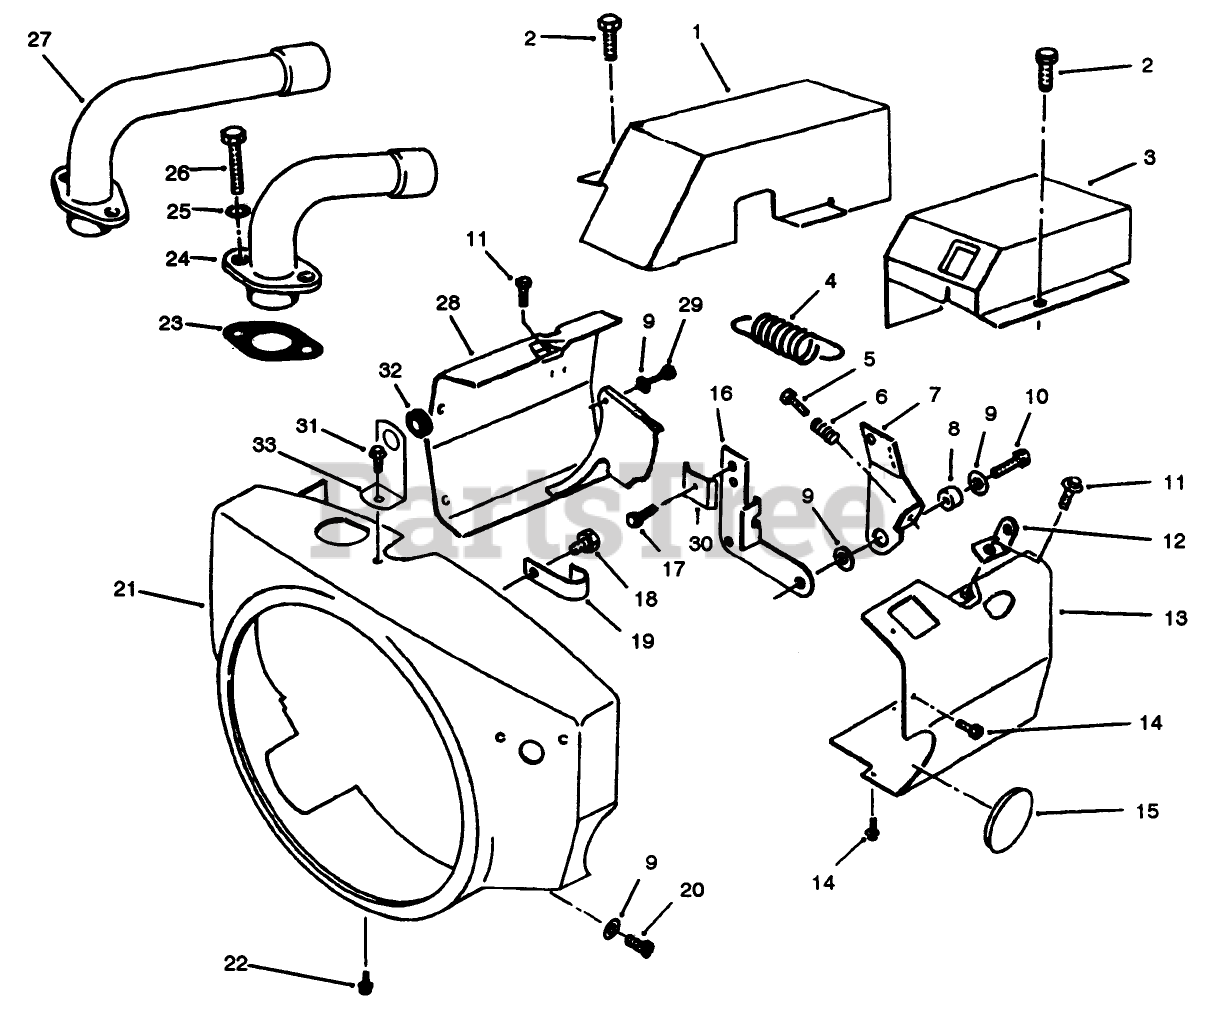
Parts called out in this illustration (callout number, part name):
1	LH EXHAUST TUBE COVERR
2	HX WSHR HD CAPSCREW
3	RH EXHAUST TUBE COVERR
4	SPRING
5	SCREW-TAP
6	SPRING
8	BUSHING
9	WASHER-FLAT
10	SCREW-HWH
11	SCREW-HHF
12	Bracket-Lift
13	CYL AIR HOUSING ASSY
14	SCREW-HWH
15	AIR SEAL GROMMET
16	BRACKET-GOVERNOR
17	SCREW-TAPPING
18	SCREW-HHF
19	CLIP-WIRE
20	SCREW-HH
21	Housing-Blower
22	HEX HD CAPSCREW
23	GASKET
24	EXHAUST TUBE
25	WASHER-FLAT
26	SCREW-HH
27	EXHAUST TUBE
28	Housing-L.H.
29	SCREW-HH
31	SCREW-HWHTF
32	GROMMET
33	FUEL LINE BRACKET
